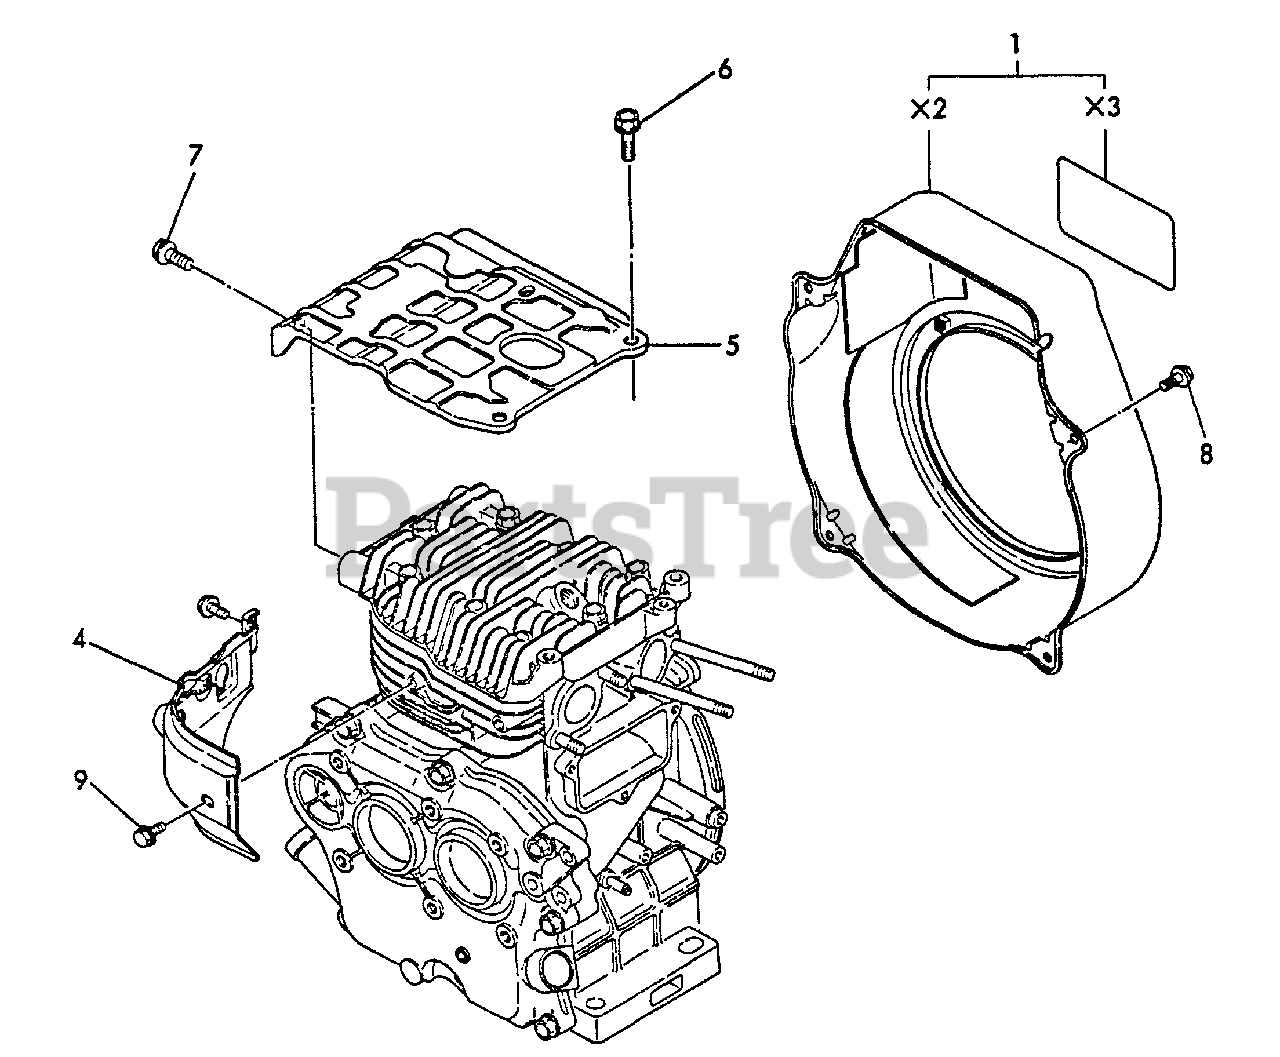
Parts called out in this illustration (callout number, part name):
1	COVER, FAN
4	SHIELD, CYLINDER
5	COVER, HEAD
6	BOLT - 8X14 -- PLATED
7	BOLT - 8X20 -- PLATED
8	BOLT - 6X8 -- PLATED
9	BOLT - 6X8 -- PLATED
